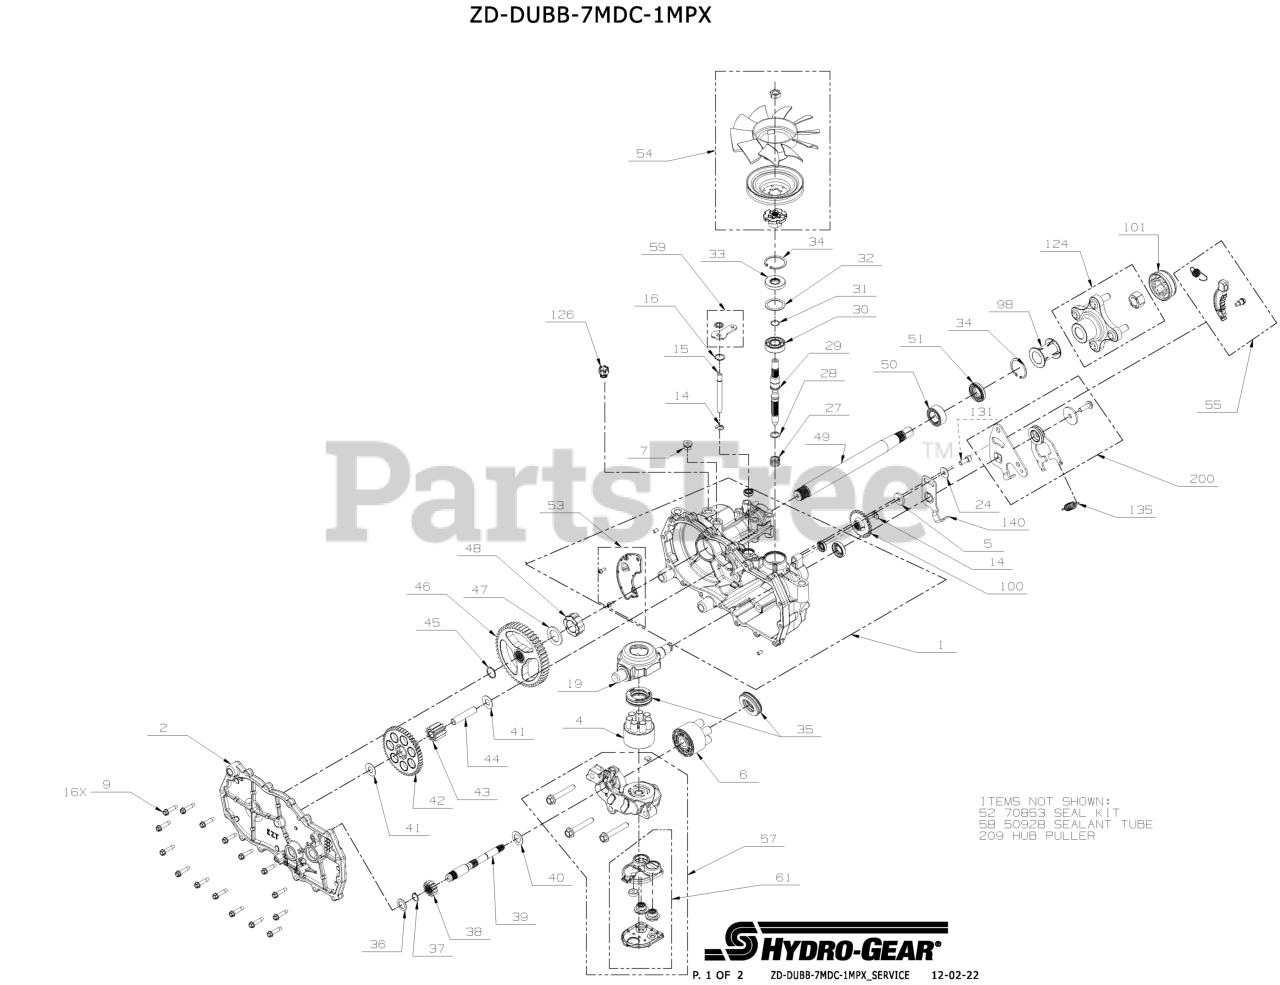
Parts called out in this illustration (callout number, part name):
1	KIT MAIN HOUSING - LH
2	KIT SIDE HOUSING - LH
4	ASSY, BLOCK 7 PISTON
6	KIT, 10 CC BLOCK
7	PLUG, STEEL (WITH SEAL)
9	SCREW,HEX WASHER 1/4-20X1.125
14	RING. RETAINING
15	ROD, BYPASS
16	RING, RET .750
19	TRUNNION, SWASHPLATE
27	SPRING. BLOCK
28	WASHER. THRUST .59 X .79 X .04
29	SHAFT, INPUT
30	BRG, BALL 17X40X12
31	RING, RET WIRE .561 ID
32	WASHER 1.23X1.56X.04
34	RING, RET 1.56 INT
35	BEARING. THRUST 30 X 52 X 13
36	WASHER, .63 X 1.00 X .05 FLAT
37	RETAINING RING, MOTOR SHAFT
39	SHAFT, MOTOR
40	WASHER .71 X 1.16 X .04
41	WASHER .5X1.0X.032
43	GEAR, 10T JACKSHAFT
44	PIN, JACKSHAFT
45	SPIRAL RETAINING RING
46	GEAR 52T BULL
48	INBOARD SLEEVE BEARING
49	SHAFT, AXLE
52	KIT, SEALS AND RETAINING
53	KIT, EXPANSION PLATE LH
54	KIT, FAN/PULLEY
55	KIT, BRAKE ARM
57	KIT,CENTER SECTION W/FILTER LH
58	SEALANT TUBE 10.1OZ.
59	KIT, BYPASS ARM
61	KIT, FILTER
100	DISC, COG BRAKE
124	KIT, HUB 4 BOLT
126	ASSEMBLY, FITTING 9/16-18 BREATHER
131	KIT, RTN SCREWS
135	SPRING, EXTENSION
140	ARM, NEUTRAL LEFT
200	BI-DIRECTIONAL KIT
209	HUB PULLER 5 BLT HYDGEAR 72320
